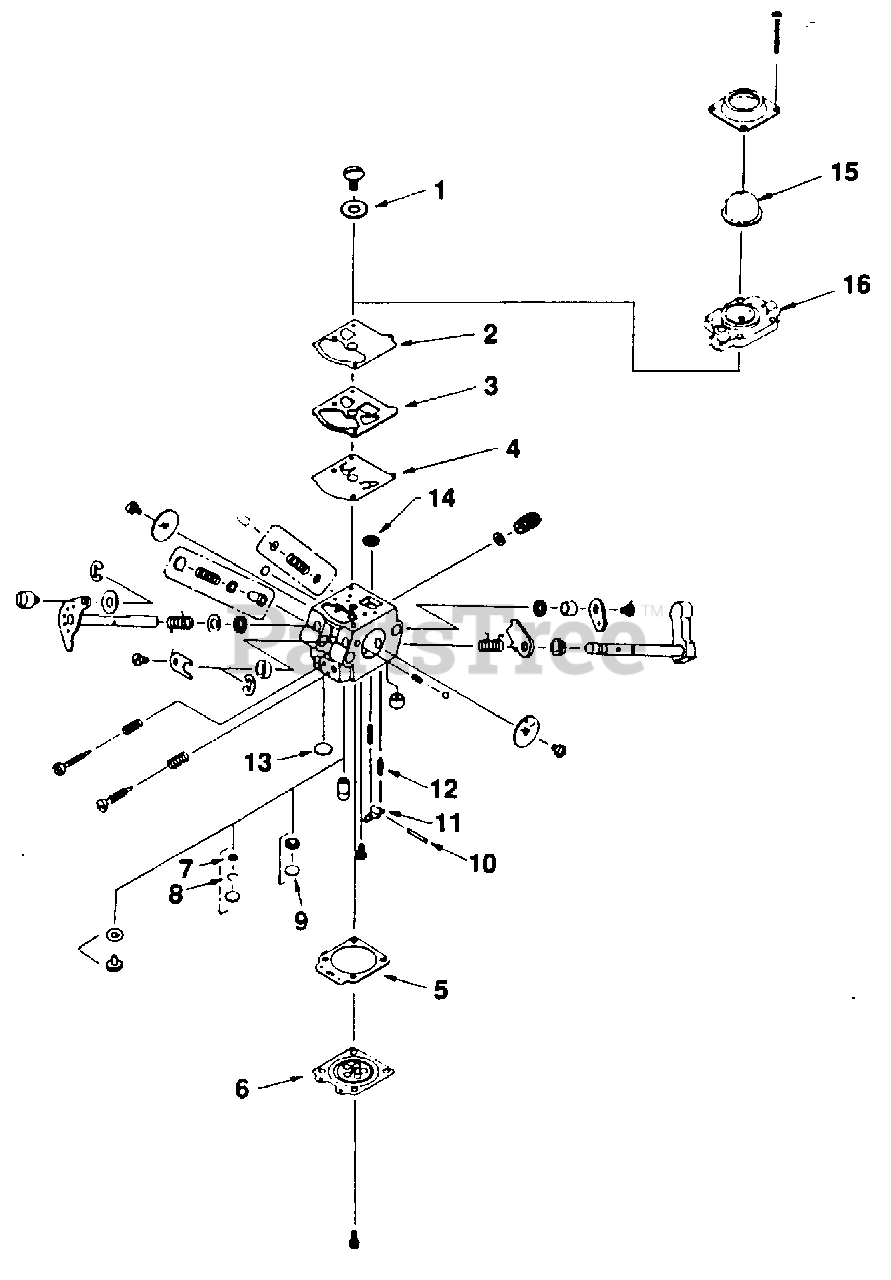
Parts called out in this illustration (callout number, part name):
1	Repair Kit
2	Repair Kit
3	Repair Kit
4	Repair Kit
5	Repair Kit
6	Repair Kit
7	Repair Kit
8	Repair Kit
9	Repair Kit
10	Repair Kit
11	Repair Kit
12	Repair Kit
13	Repair Kit
14	Repair Kit
15	Primer Bulb
16	Primer Base
